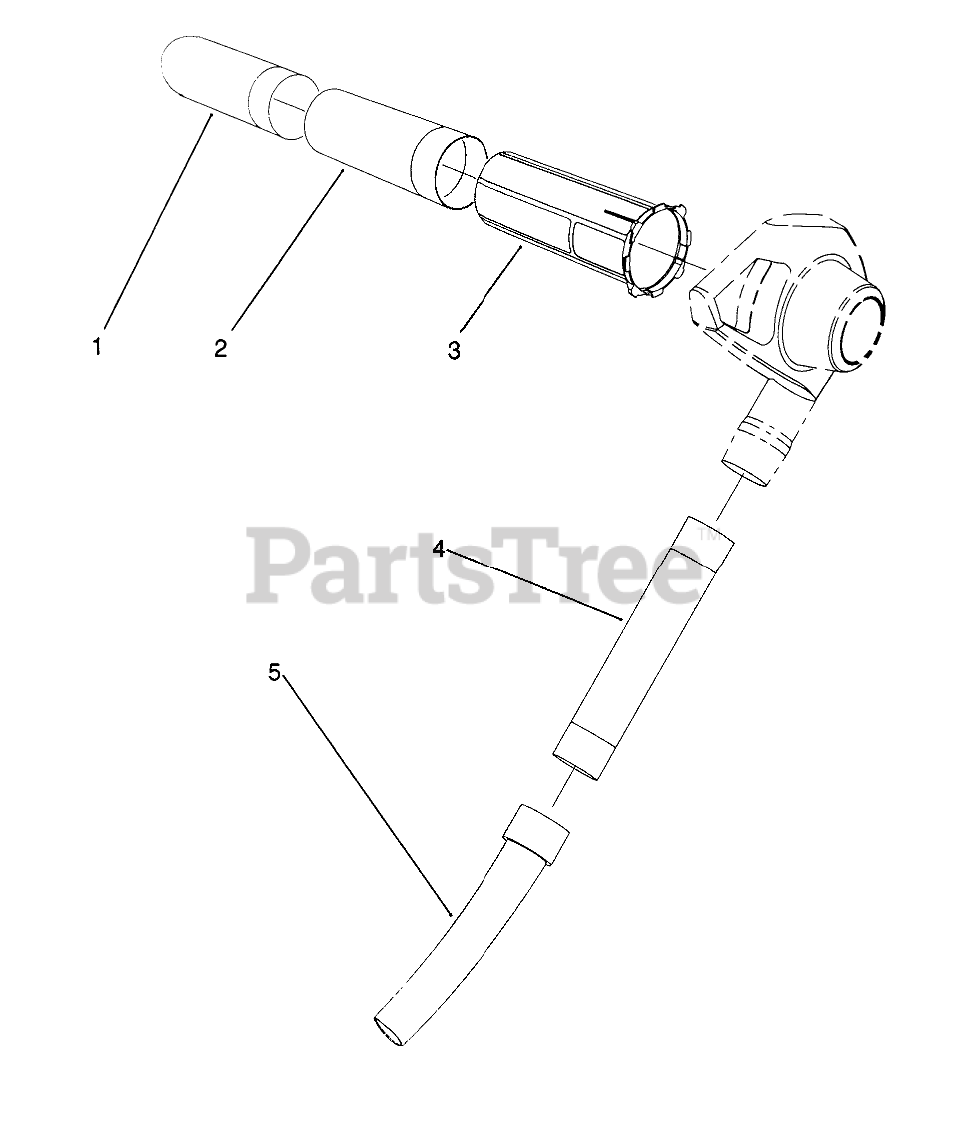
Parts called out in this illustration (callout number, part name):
1	LOWER VAC TUBE
2	MIDDLE VAC TUBE
3	UPPER VAC TUBE
4	BLOWER TUBE
5	MID BL-DISCHARGE TUBE
